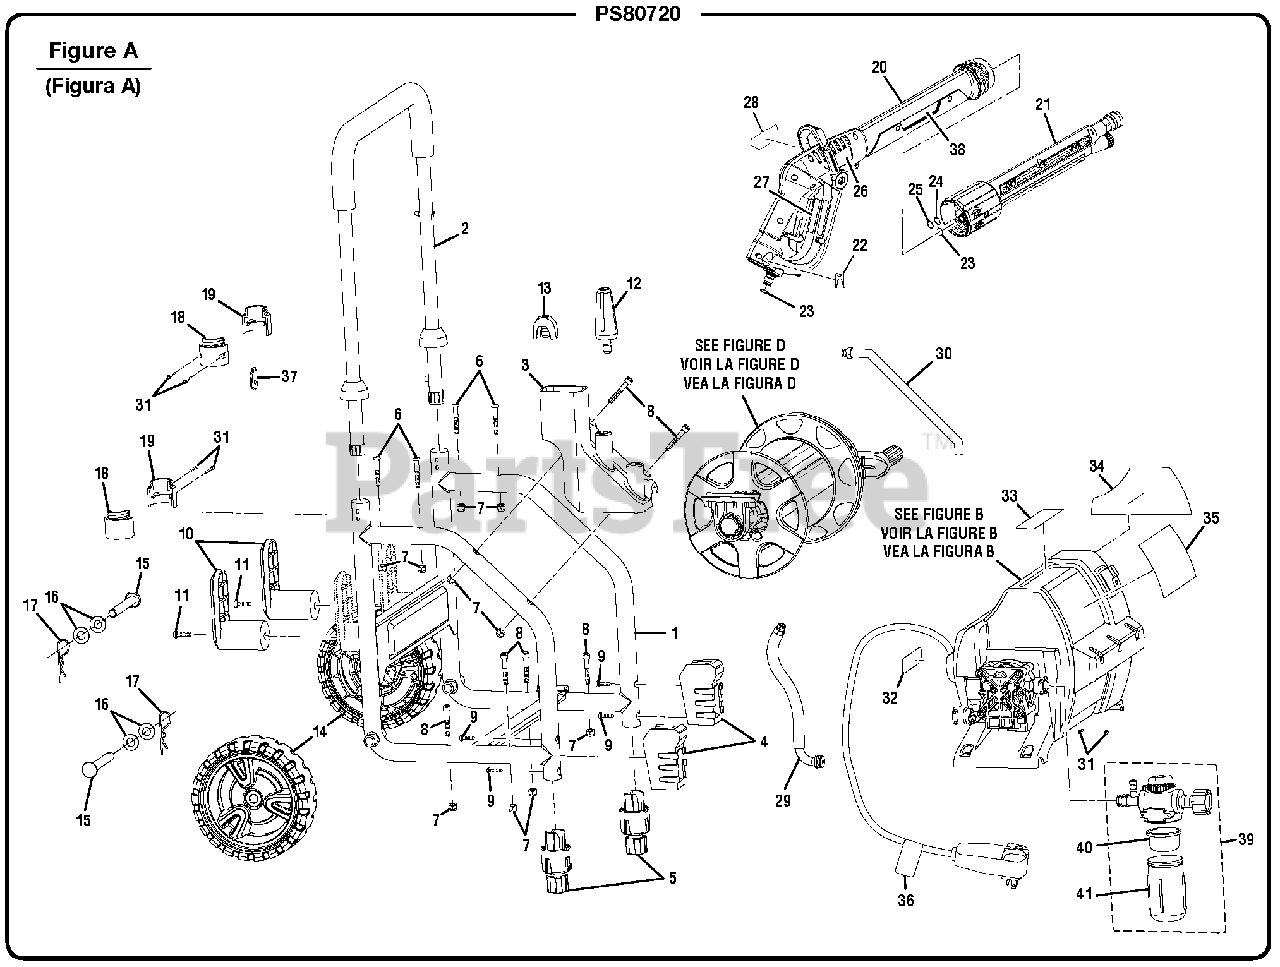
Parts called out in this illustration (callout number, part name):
1	Frame Assembly
2	Handle Assembly
3	Trigger Handle Holder
4	Foot Cover
5	Foot Assembly
6	Bolt (M6 x 40 mm, Pan Hd.)
7	Lock Nut (M6)
8	Screw (M6 x 40 mm)
9	Screw (M4 x 12 mm)
10	Cord Wrap Arm
11	Bolt (M8 x 20 mm, Hex Soc. Hd.)
12	Turbo Nozzle
13	Spray Nozzle (15deg)
14	Wheel Assembly
15	Wheel Axle
16	Washer (ID12.5 x OD24 x 2t)
17	Hitch Pin
18	Inner Handle Clamp
19	Outer Handle Clamp
20	Trigger Handle Assembly
21	Lance Assembly
22	High Pressure Hose Clip
25	Backup Ring
26	Logo Label
27	Trigger Rating Label
28	Warning Label
29	High Pressure Hose
30	Low Pressure Hose
31	Screw (M3 x 10 mm)
32	Data Label
33	Hydrosurge Label
34	Danger Label
35	Performance Label
36	Warning Label (UL)
37	Handle Release Button
38	Logo Label (Hydrosurge)
39	G-Clean Assembly (Inc. Key Nos. 40-41)
40	Water Inlet Filter
41	Detergent Container
